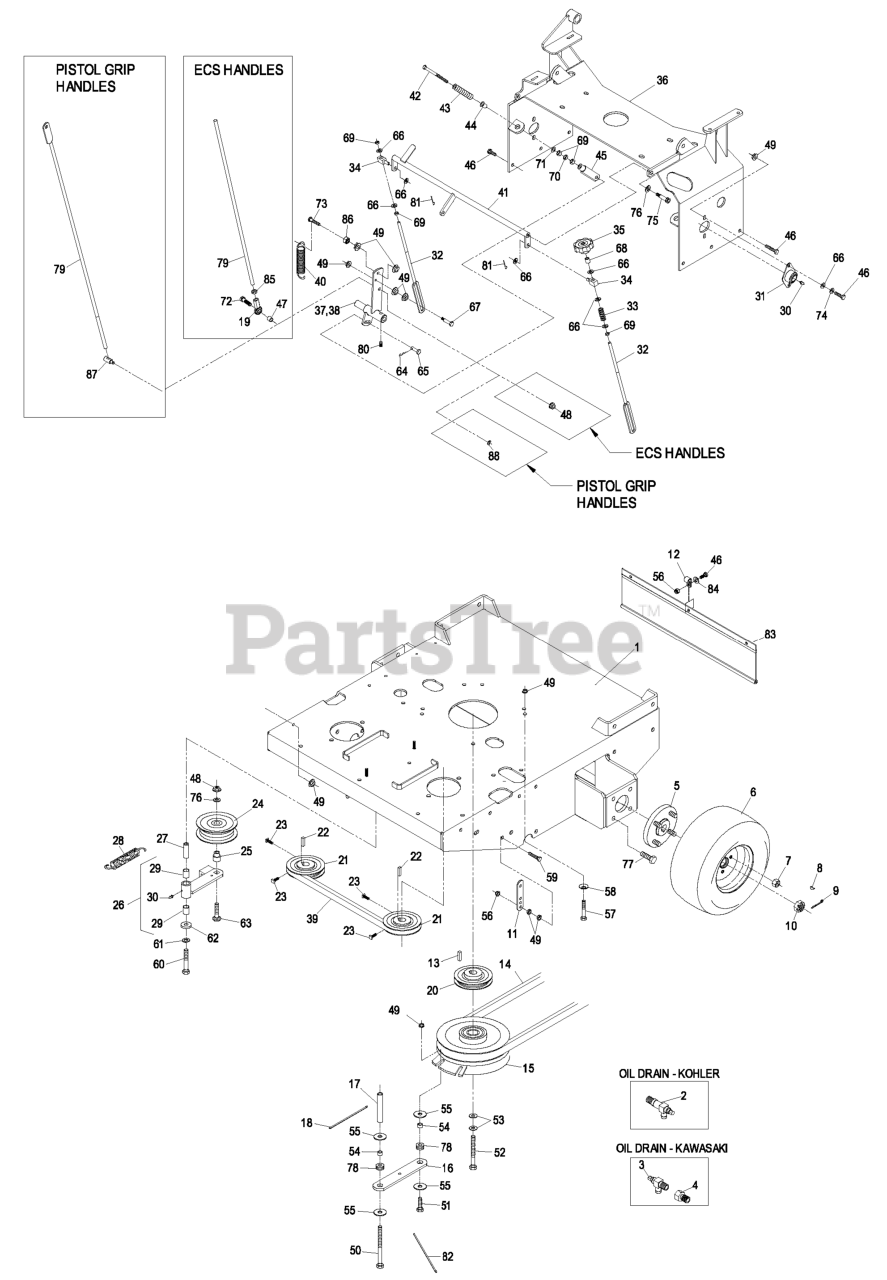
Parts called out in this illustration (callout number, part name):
1	Eng Deck 103-2963-01 W/ Decals
2	VALVE-DRAIN, OIL
3	VALVE-DRAIN, OIL
4	ADAPTER
6	ASM, DRIVE TIRE
7	NUT-LUG
8	KEY-WOODRUFF
9	PIN-COTTER
10	NUT-HEX, SLOTTED
11	TAB-SPRING, EXTENSION
12	CLIP-LOOM
14	BELT,B 83.65
15	CLUTCH ASM
16	STRAP-CLUTCH, BRAKE
18	TIE-CABLE
19	JOINT-BALL END, LH
20	PULLEY
21	SHEAVE ASM
23	SCREW-SET
25	BUSHING-IDLER
26	IDLER ARM ASM
27	BUSHING
28	SPRING-EXTENSION
29	SLEEVE-BEARING
30	FITTING-GREASE
31	BEARING-FLANGE, SIDE
32	LINK,SPEED CONTROL
33	SPRING-COMPRESSION
35	KNOB-TRACKING
37	WLD,LH CONTROL ARM
40	SPRING-EXTENSION
41	WLD,CRANK SPEED CNTRL
42	BOLT-RETURN, NEUTRAL
43	SPRING,COMPRESSION (NEUT)
44	BUSHING-FLANGED
45	YOKE-ADJUSTABLE
46	SCREW-HH
47	TUBE,PUMP LINK SPACER
48	NUT-HHF, WHIZ
50	SCREW-HH
51	SCREW-HH
52	SCREW-HH
53	WASHER-SPRING
56	NUT-LOCK, NI
57	SCREW-HH
58	WASHER-SPRING
59	BOLT-TAP, HH
60	BOLT-CARR
61	WASHER-LOCK
63	SCREW-CARR
64	PIN-COTTER
65	PIN-CLEVIS
66	WASHER-PLAIN
67	SCREW-HH
69	NUT-HEX
70	NUT-JAM
71	WASHER-FLAT
72	SCREW-HH
73	SCREW-HH
74	WASHER-LOCK
75	SCREW-HSH
76	WASHER-FLAT
77	SCREW-HHF
78	GROMMET
79	LINK,DRIVE (PLTD)
80	SCREW-SET
81	PIN-COTTER
82	TIE-PLASTIC
83	SHIELD,DRAG
84	WASHER-FLAT
85	NUT-HEX JAM, LH
86	Nut, Jam 5/16-18
87	SWIVEL-LEVER, DRIVE
88	RING-RETAINING
